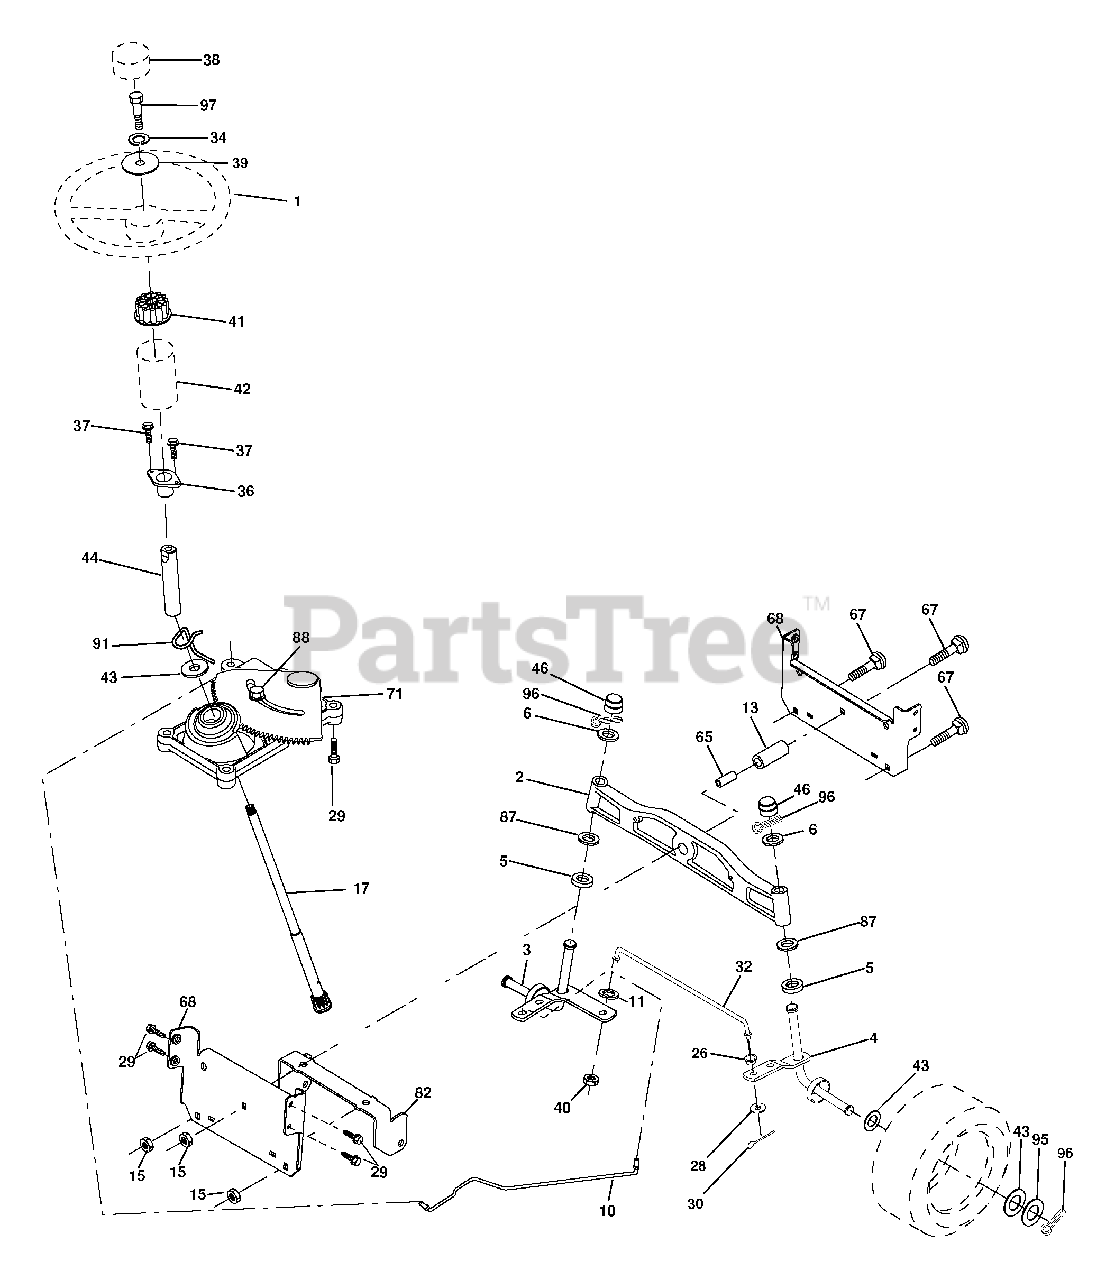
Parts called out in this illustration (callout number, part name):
1	Wheel Steering
2	Axle Asm
3	Spindle Asm LH
4	Spindle Asm RH
5	Bearing Race Thrust Harden
6	Washer 25/32 x 1-5/8 x 16 Ga.
8	Ring Klip #t5304-75
10	Link Drag
11	Washer Lock Hvy Hlcl Spr 3/8
13	Spacer Brg Axle Front
15	Nut Hex Flange Lock
17	Shaft Asm Steering
26	Bushing Link Drag
28	Washer 13/32 x 7/8 x 16 Ga.
29	Screw 3/8-16 x .75
30	Pin Cotter 1/8 x 3/4
32	Rod Tie
34	Washer Lock Hvy Hlcl Spr 5/16
36	Bushing Strg
37	Screw
38	Insert Cap Strg Wh
39	Washer 11/32 ID x 2-3/8 OD 12 Ga.
40	Crownlock nut
41	Adaptor Wheel Strg
42	Boot Steering Dash
43	Washer 25/32 x 1 1/4 x 16 Ga.
44	Extension Steering Shaft
46	Cap Spindle Fr Top Blk
65	Spacer Brace Axle
67	Bolt RDHD SQNK 3/8-16 x 2 1/4
68	Axle, Brace
71	Steering Asm
82	Bracket Susp Chassis Front
87	Washer Flat .781 x 1 1/2 x .14
88	Bolt Shoulder 7/16-20 unc
91	Clip Steering
95	Washer Harden .739 x 1.637 x .060
96	Pin Cotter
97	Bolt 5/16-18 unc x 4" L Gr. 5
